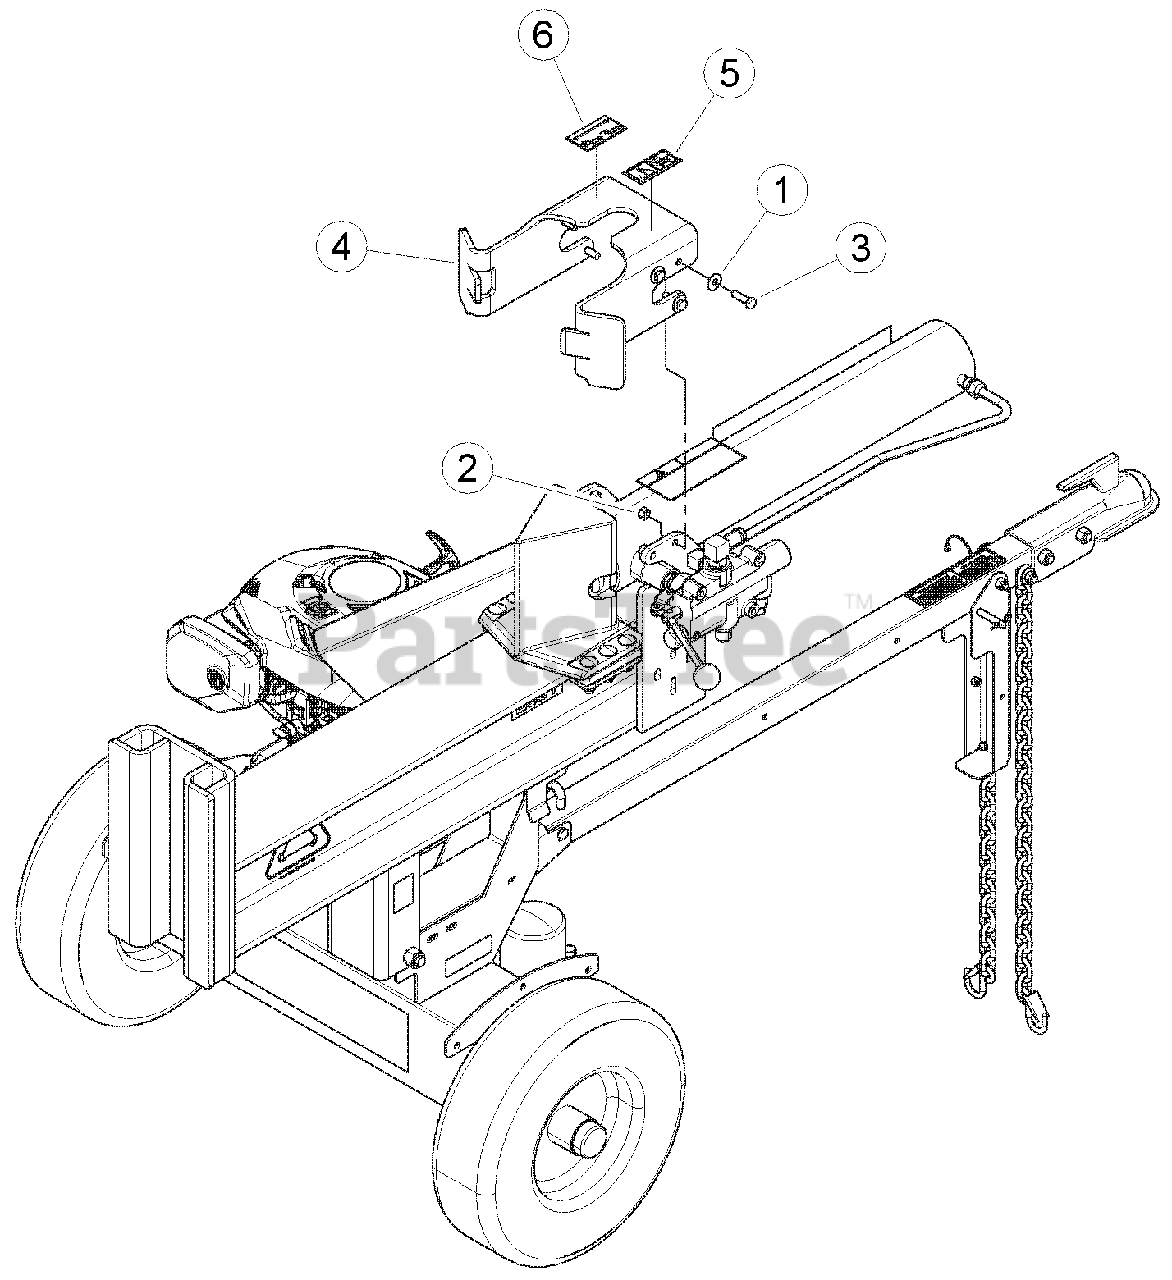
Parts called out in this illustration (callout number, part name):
1	WASHER, 3/8" FLAT ZP (67PCS/LB)
2	NUT, 3/8" CENTERLOCK ZP
3	BOLT, 3/8 X 1-1/4" HEX HD GR5 ZP
4	ASSEMBLY, STRIPPER PLATE WIDE, SERVICE PART
5	DECAL, CRUSHING ISO
6	DECAL, CYLINDER OPERATION ISO
